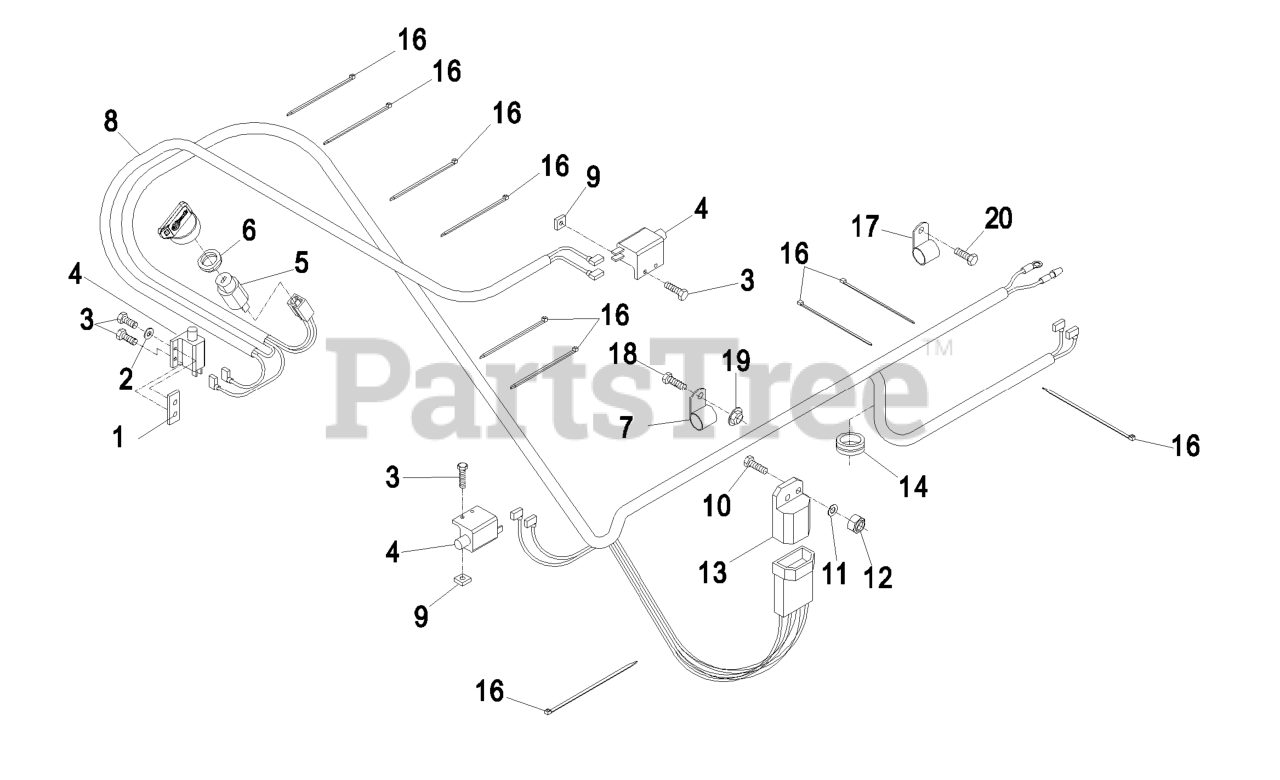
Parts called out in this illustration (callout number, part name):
1	PLATE-TAPPED
2	WASHER-FLAT
3	SCREW-PPH
4	SWITCH-OPEN, NORMALLY
5	SWITCH & KEY (INCLUDES NU
6	NUT-SWITCH, IGNITION
7	CLIP-LOOM
8	HARNESS-WIRING
9	NUT-SQH
10	SCREW-HH
11	WASHER-FLAT
12	NUT-LOCK, NI
13	MODULE-INTERLOCK
14	GROMMET
16	TIE-CABLE
17	CLIP-LOOM
18	SCREW-HH
20	SCREW-HH
